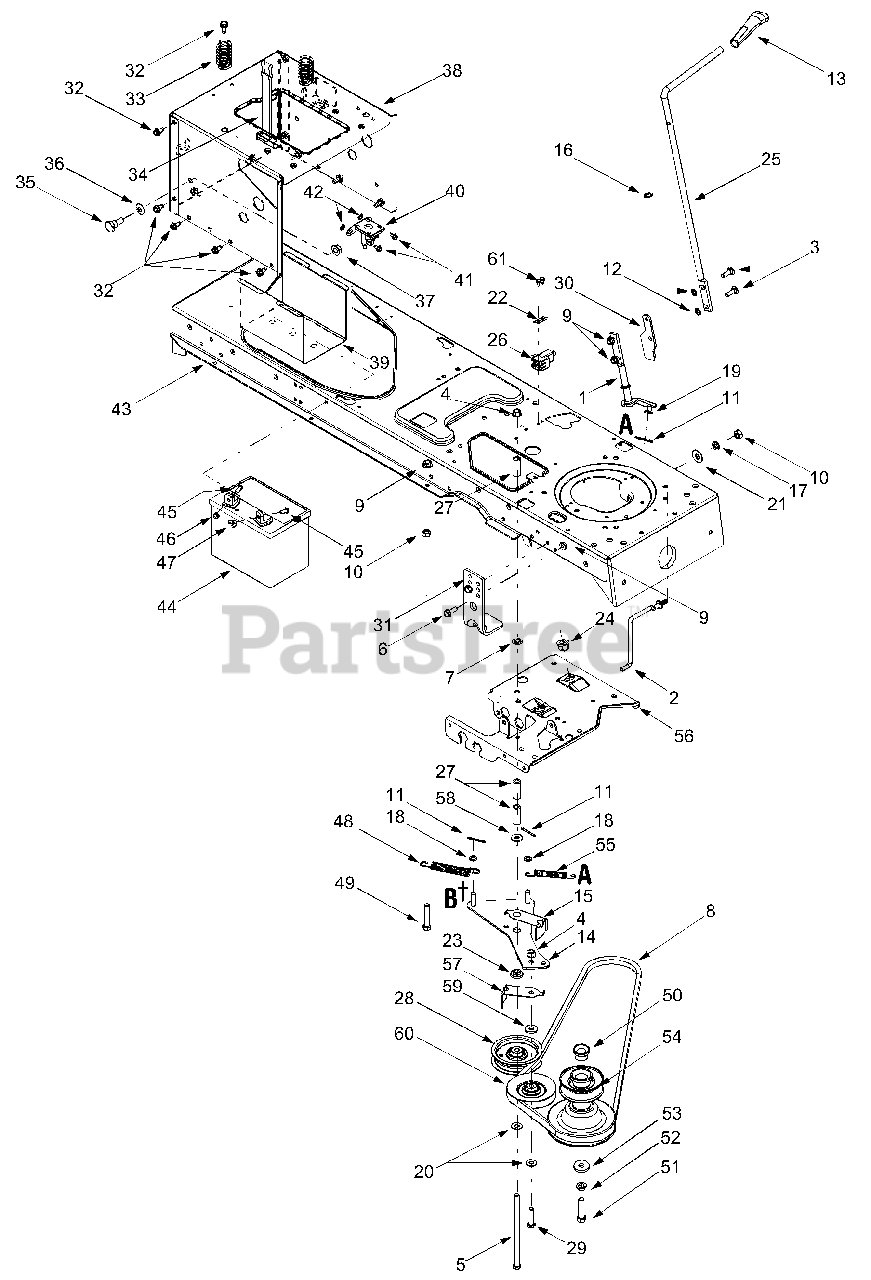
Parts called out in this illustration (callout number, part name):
1	PTO Engage Lever Assembly
2	Belt Keeper Rod
3	Carriage Screw, 5/16-18 x 1.00
4	Flange Lock Nut, 3/8-16
5	Hex Cap Screw, 3/8-16 x 7.0
6	Hex Head Washer Screw, 5/16-18 x .875
7	Push Nut, 3/8
8	PTO Belt (Models w/ 46-inch deck)
9	Flange Lock Nut, 5/16-18
10	Hex Nut, 5/16-18
11	Cotter Pin, 1/8 x 1.25
12	Speed Nut, .3125
13	PTO Knob
14	PTO Engagement Plate Assembly
15	Belt Guard
16	Flat Washer, .510 x .750 x .033
17	Lock Washer, 5/16
18	Flat Washer, .385 x .62 x .063
19	Flat Washer, 5/16
20	Flat Washer, .406 x .875 x .059
21	Bell Washer, .35 x .872 x .060
22	Switch Plate
23	Shoulder Spacer, .380
24	Hex Split Flange Bearing, .5
26	Interlock Switch
27	Spacer, 3/8 x 1.54
28	Idler Pulley, Flat, 3.5
29	Hex Cap Screw, 3/8-16 x 1.5
32	Self Tapping Screw, 5/16-18 x .625
33	Compression Spring, 1.28 x 3.125
34	Battery Strap
35	Shoulder Screw, .625 x .5, 7/16-20
36	Bell Washer, .45 x 1.0 x .062
37	Flange Lock Nut, 7/16-20
41	Self Tapping Screw, 1/4-20 x .5
42	Lock Washer, 1/4
45	Hex Cap Screw, 1/4-20 x .62
46	Hex Sems Nut, 1/4-20
47	Wing Nut, 1/4-20
48	Extension Spring, .50 x 5.0
49	Hex Cap Screw, 5/16-18 x 1.75
50	Spacer Cup
51	Hex Head Cap Screw, 7/16-20 x 1.25
52	Lock Washer, 7/16
53	Flat Washer, .450 x 1.25
54	Engine Pulley, 3.56 OD x 5.56
55	Extension Spring, .75 x 6.75
57	Belt Guard
58	Flat Washer, .38 x .93 x .110
59	Flat Washer, .385 x 1.0 x .135
60	Idler Pulley, V-Type, 4.0
61	Screw, #10-16 x .5
